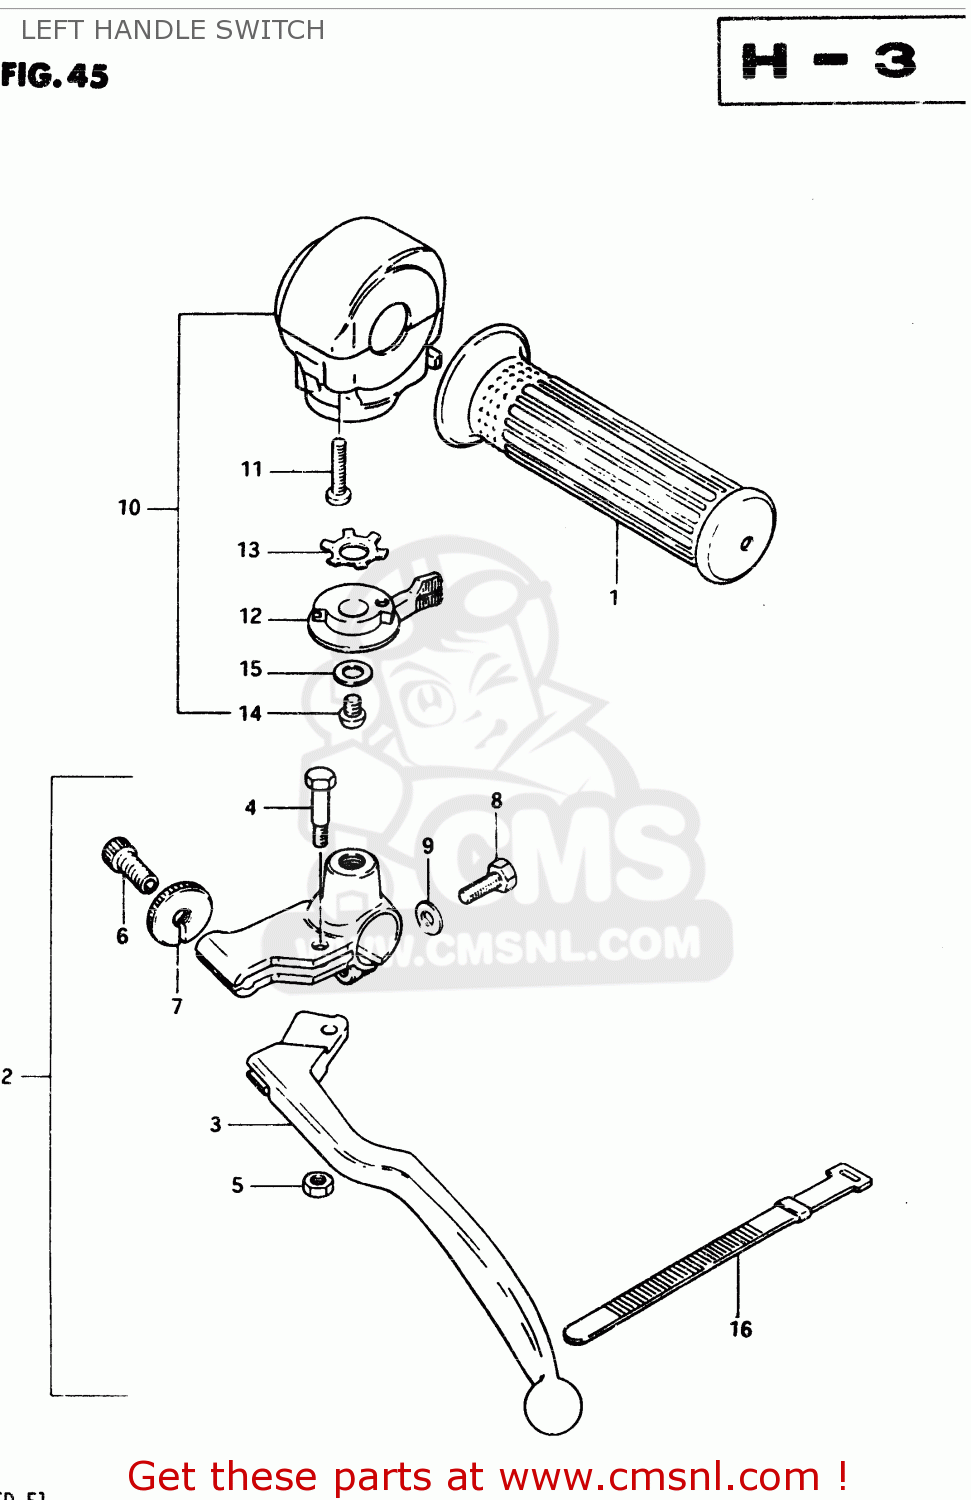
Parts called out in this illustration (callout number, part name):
1	GRIP,LEFT
2	LEVER ASSEMBLY,CLUTCH
3	LEVER,CLUTCH
4	BOLT,LEVER
5	NUT 6MM
6	ADJUSTER,CABLE
7	NUT,CABLE ADJUSTER LOCK
8	BOLT,CLUTCH LEVER HOLDER
9	SPACER
10	SWITCH ASSY, HANDLE LH
11	SCREW
12	LEVER,STARTER
13	WASHER
14	SCREW
15	WASHER 6MM
16	CLAMP(L:120)
